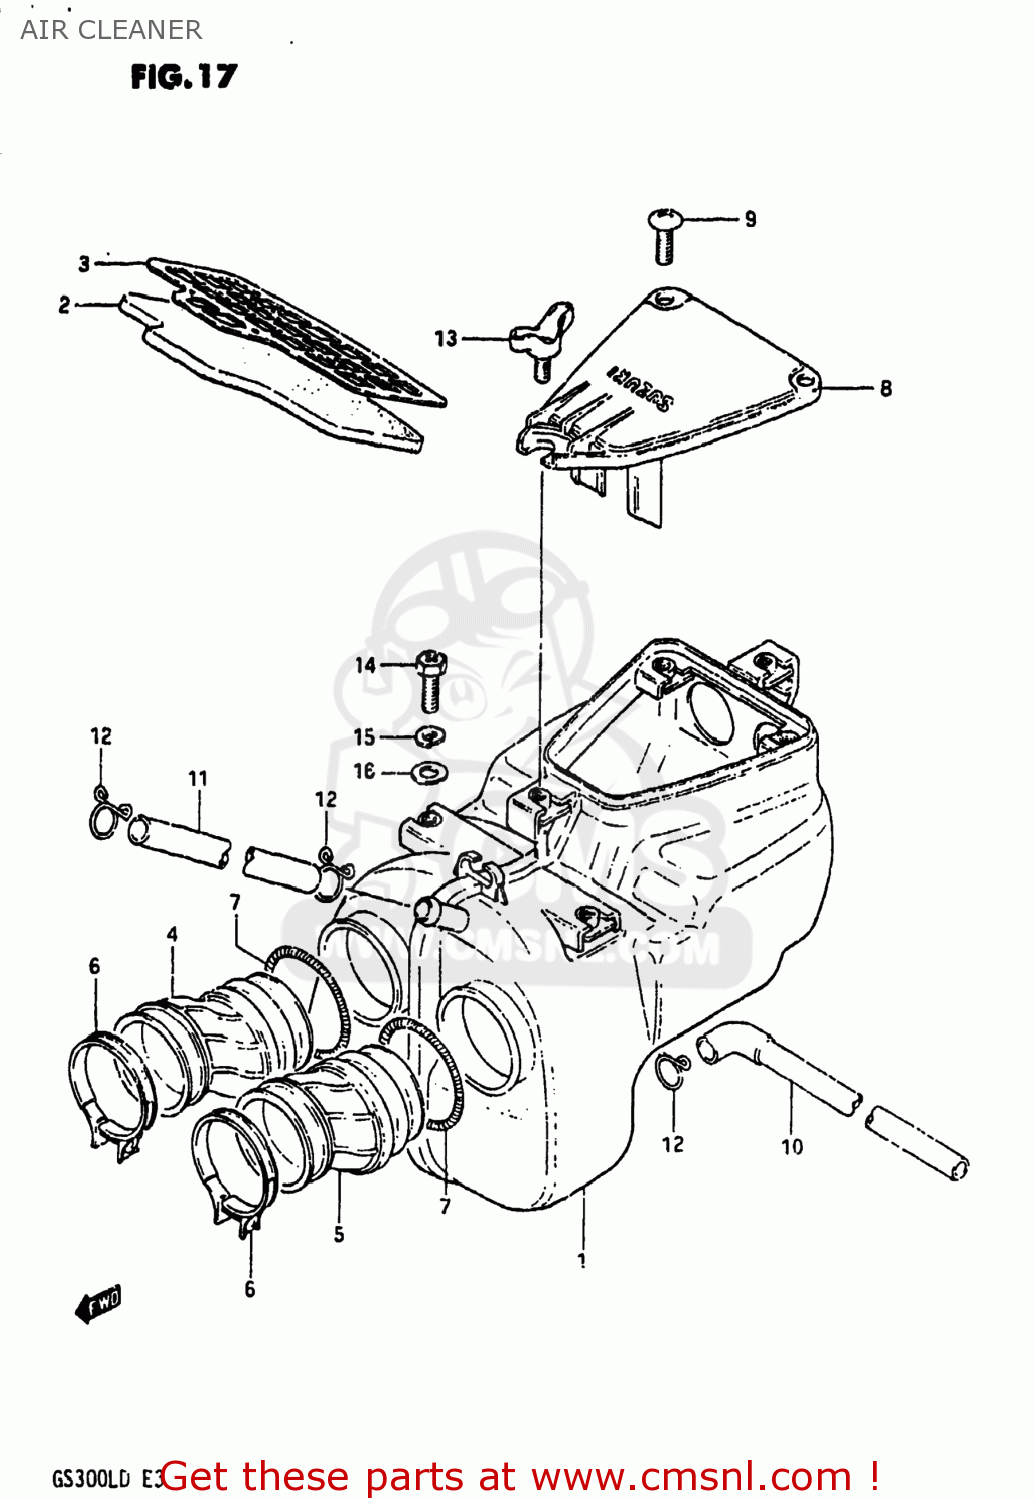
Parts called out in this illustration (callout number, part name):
1	CLEANER ASSEMBLY,AIR
2	FILTER
3	HOLDER,OUTER
4	TUBE,OUTLET,R
5	TUBE,OUTLET,L
6	CLAMP
7	CLAMP,CLEANER SIDE
8	CAP,AIR CLEANER
9	SCREW
10	DRAIN TUBE
11	TUBE,BREATHER
12	CLAMP
13	BOLT, WING
14	SCREW(6X12)
15	LOCK WASHER
16	WASHER
